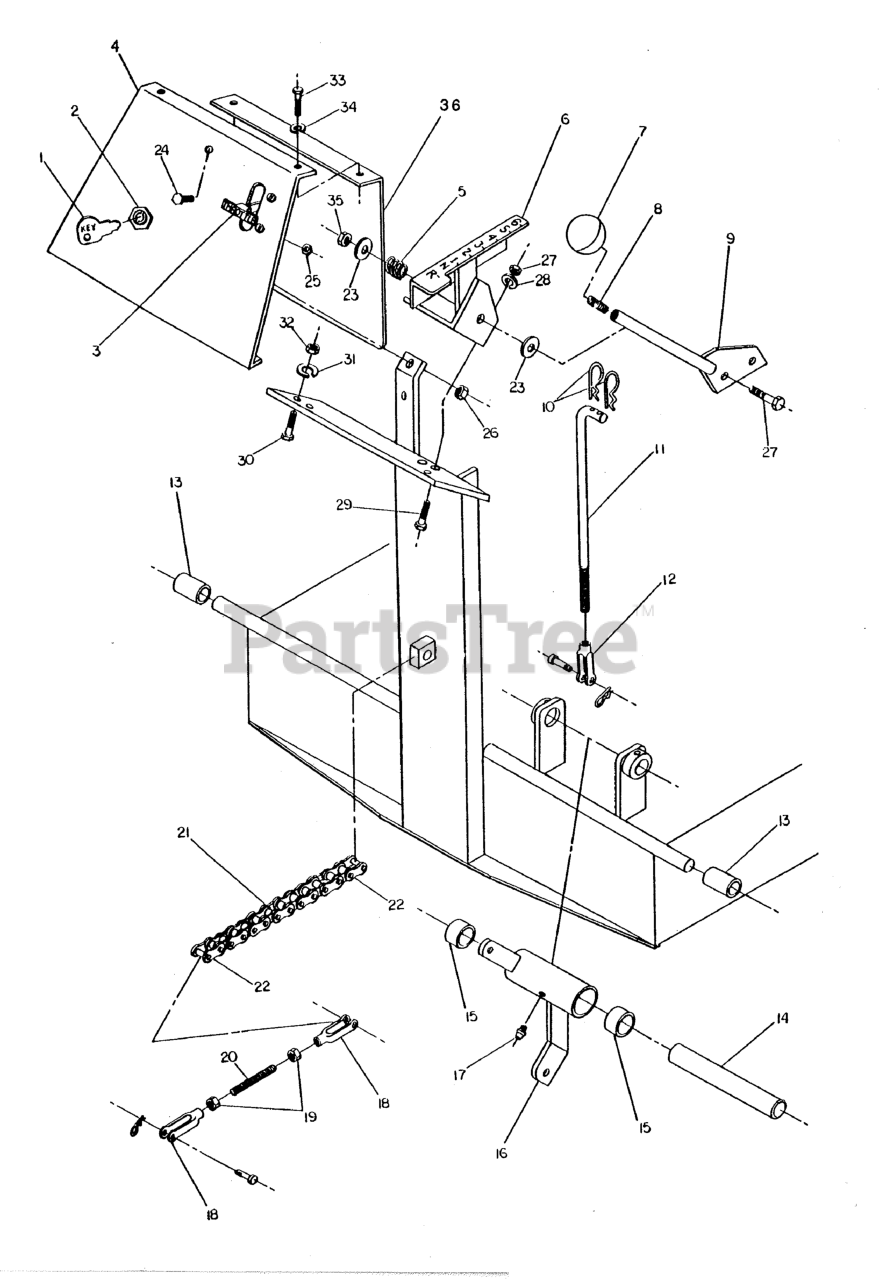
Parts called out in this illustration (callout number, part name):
1	Ignition Key
2	SWITCH, Ignition
3	CABLE, Throttle, 31"
4	Control Panel
5	SPRING, Compression
6	Shifter Guide
7	Black Knob
8	STUD, 5/16-18 x 1"
9	Shifter Handle
10	HAIRPIN CLIP
11	Shifter Adjustment Rod
12	CLEVIS, 3/8-24, Plastic
14	3/4" Diameter Shafting 6-1/4"
15	BUSHING, Brass
16	Transmission Bell Crank
17	GREASE FITTING
18	CLEVIS, 5/16-24, Plastic
19	5/16 Hex Nut
20	STUD, 5/16-24 x 3"
21	Plated #60 Chain
22	Plated #60 Connector
23	3/8 Flat Washer
24	5/16-18 x 1" Hex Head Cap Screw
25	10/32 Nut
26	5/16-18 Serrated Flange Nut
27	1/4-20 Nut
28	1/4 Lock Washer
29	1/4-20 x 1 Hex Head Cap Screw
30	1/4-20 x 3/4 Hex Head Cap Screw
31	1/4 Lock Washer
32	1/4 Nut
33	1/4-20 x 5/8 Hex Head Cap Screw
34	1/4 Lock Washer
35	3/8-16 Lock Nut
36	Control Panel Cover
